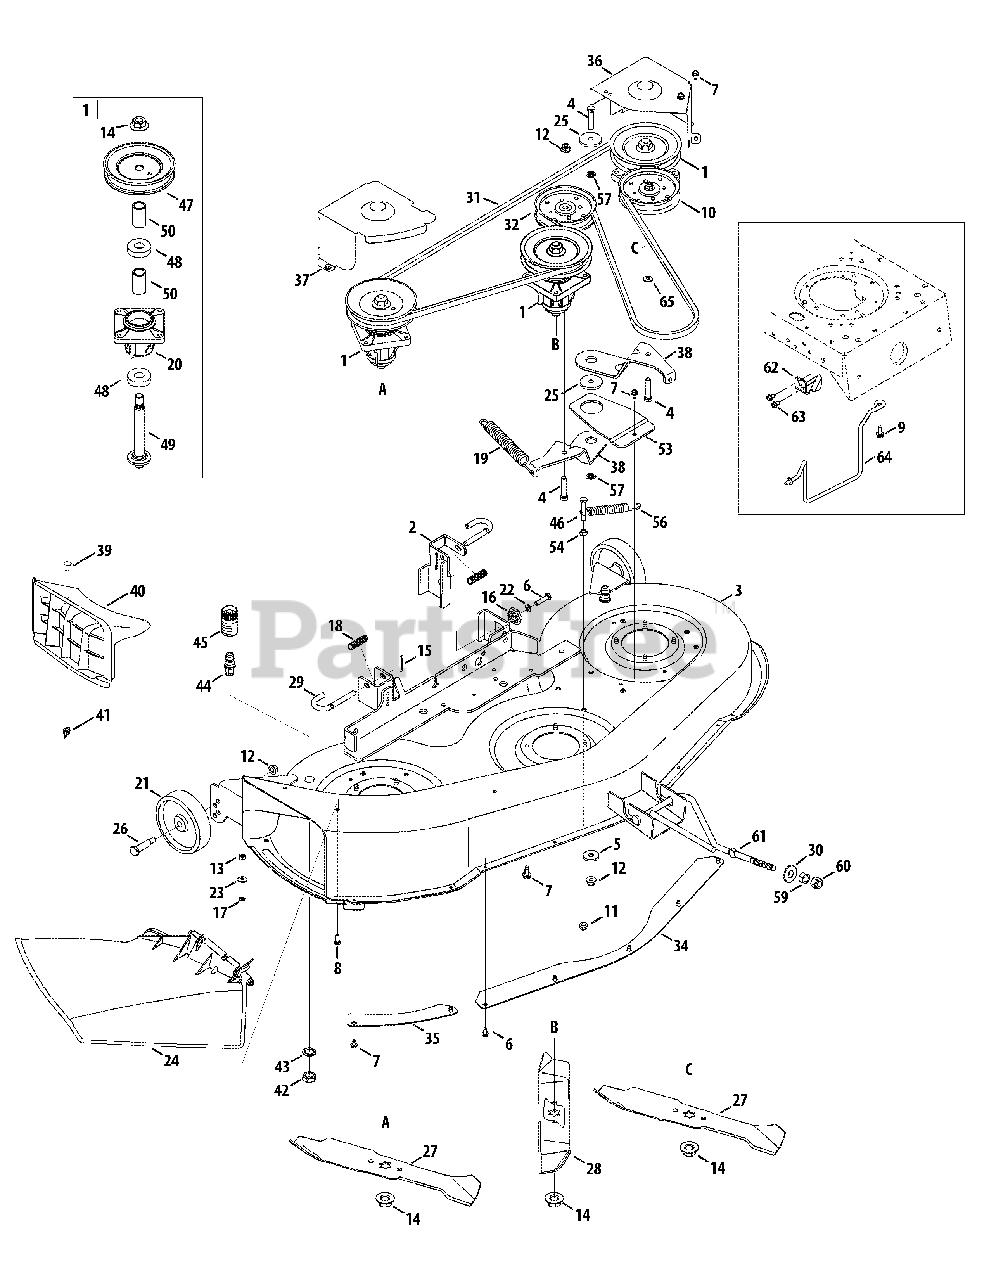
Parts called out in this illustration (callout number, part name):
1	Spindle Ass’y 5.75 Dia w/grease fitting
4	Hex Screw 3/8-16 x 1.75
5	Flat Washer .450 x 1.25 x .164
6	Hex Bolt 5/16-18 x 1.25
7	Hex Wash S-Tapp Scr 1/4-20 x .50
8	Hex Cap Bolt 1/4-20 x .75" Lg.
9	Hex Wash. Hd. Scr. 5/16-18 x .75 Lg.
10	Flat Idler Pulley 3.5 OD
11	Flange Locknut 5/16-18 Gr. F, Nylon
12	Flange Lock-Nut 3/8-16 Gr. F Nylon
13	Hex Nut 1/4-20 Gr. 5
14	Hex Flange Nut 5/8-18
15	Cotter Pin 3/32 dia x 1.00 Lg.
16	Deck Adjustment Gear
17	Bolt Retainer 1/4" x .50" OD
18	Compression Spring .531 OD x 1.75 Lg.
19	Extension Spring
20	Spindle Housing
21	Wheel Ass’y - Deck 5" x 1.38"
22	L-Wash 5/16 ID
23	Cupped Washer .265 ID x .75 OD x .062
24	Chute Deflector (Plastic)
25	Shoulder Spacer .884 x .190
26	Shoulder Bolt .498 Dia x 1.53 x 3/8-16
27	Three-in-one Blade, Star Centre 16.28"
28	Three-in-one Blade, Star Centre 14.88"
29	Deck Release Pin
30	Pivot Deck Lift Cup
31	Belt, V Type
32	Idler Poulie w/Flange 4.25 Dia
40	Mulching Plug
41	Wing Nut 1/4-20 Thd.
42	Hex Nut M16-1.5 DIN 936
43	L-Washer Internal
45	Water Nozzle Adaptor
46	Hex Hd Cap Scr. 5/16-18 x 2.0 Gr. 5
47	Deck Pulley 5.75 Dia. (42" Deck)
48	Ball Bearing 20 x 47 x 14:6204:DS
49	Spindle Shaft 6.05 Lg.
50	Spacer .792 x 1.060 x 1.860 Lg.
52	Grease Fitting
53	Support Bracket, Idler
54	Hex Nut 5/16-18 hd. (Gr. 5)
56	Extension Spring .865 x 4.68
57	Push Nut Bolt Retainer
58	Flat Washer .330 ID x 1.25 OD x .120
59	Hex Nut 1/2-13
60	Hex Nut, 1/2-13
61	Deck Front Hanger Rod
63	Hex Wash HD AB Tap Scr 5/16-12 x .75
65	Flat Washer .406 ID x .812 OD x .134
